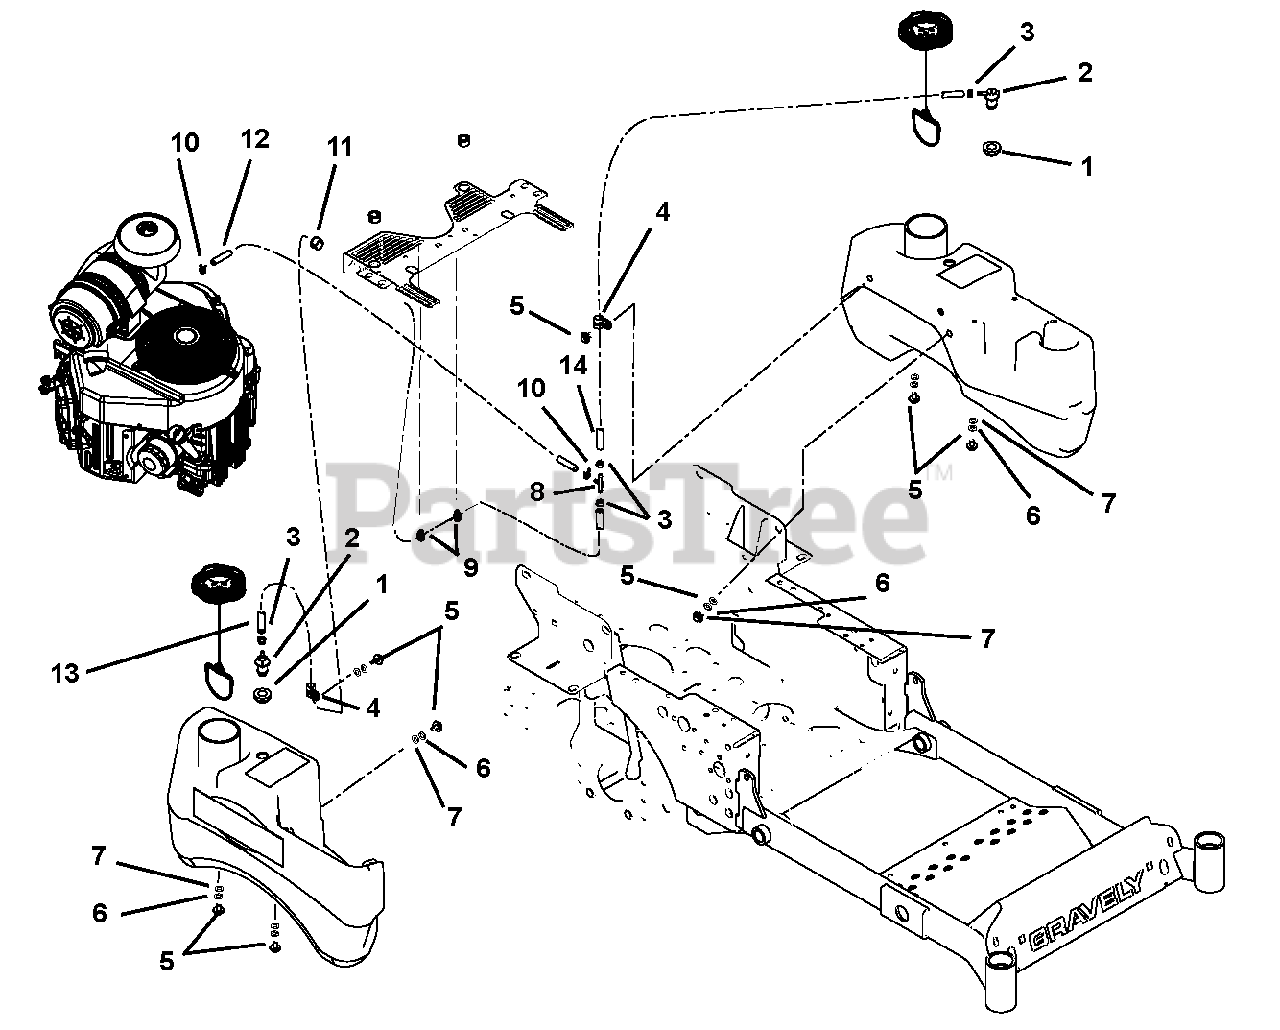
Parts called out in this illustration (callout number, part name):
2	Valve
3	Hose, Clamp
5	Bolt, .31-18 x .62
6	Washer, Locking .31 x .078 Regular
7	Washer, Flat Steel .38 x .875 x .083
8	Fitting, Tee 1/4 x 3/8
9	Clip, Routing
10	Clamp, Spring .188
11	Bushing, Snap
12	Hose, Fuel
13	Hose, Fuel
14	Hose, Fuel
